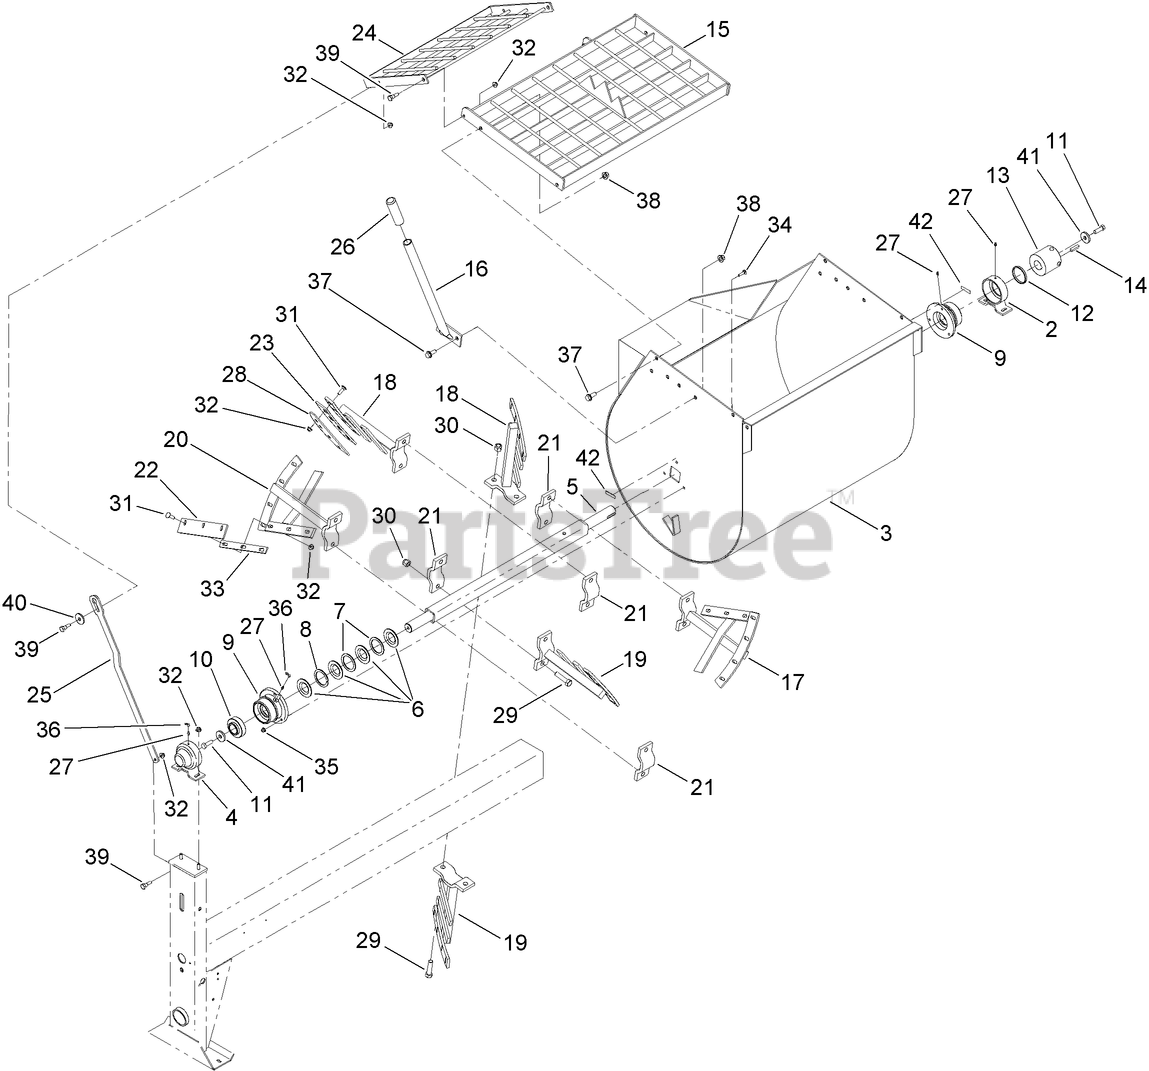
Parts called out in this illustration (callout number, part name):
2	TRUNNION
4	TRUNNION-CAPPED
5	SHAFT-DRUM
6	SEAL-DRUM
7	WASHER-FLAT
8	WASHER-SPLIT
9	HOUSING-BEARING
10	BEARING-BALL
11	SCREW-HH
12	SPACER-SHAFT, DRUM
13	COUPLING-SHAFT
14	KEY-SQUARE
16	HANDLE-DUMP
21	CLAMP-PADDLE
22	BLADE-RUBBER, SHORT
23	BLADE-RUBBER, LONG
24	GUARD-MOVEABLE
25	BAR-GUARD LIFT
26	GRIP-HAND
27	FITTING-GREASE
28	BAR-LONG, BACKER
29	SCREW-HH
30	NUT-LOCK, NI
31	BOLT-CARR
32	NUT-HF, NI
33	BAR-BACKER, SHORT
34	SCREW-CARR
35	NUT-HF, NI
36	CAP-PLUG
37	SCREW-HHF
38	NUT-LOCK
39	BOLT-SHOULDER
40	Washer-Thrust
41	WASHER-FLAT
42	DECAL-GREASE
